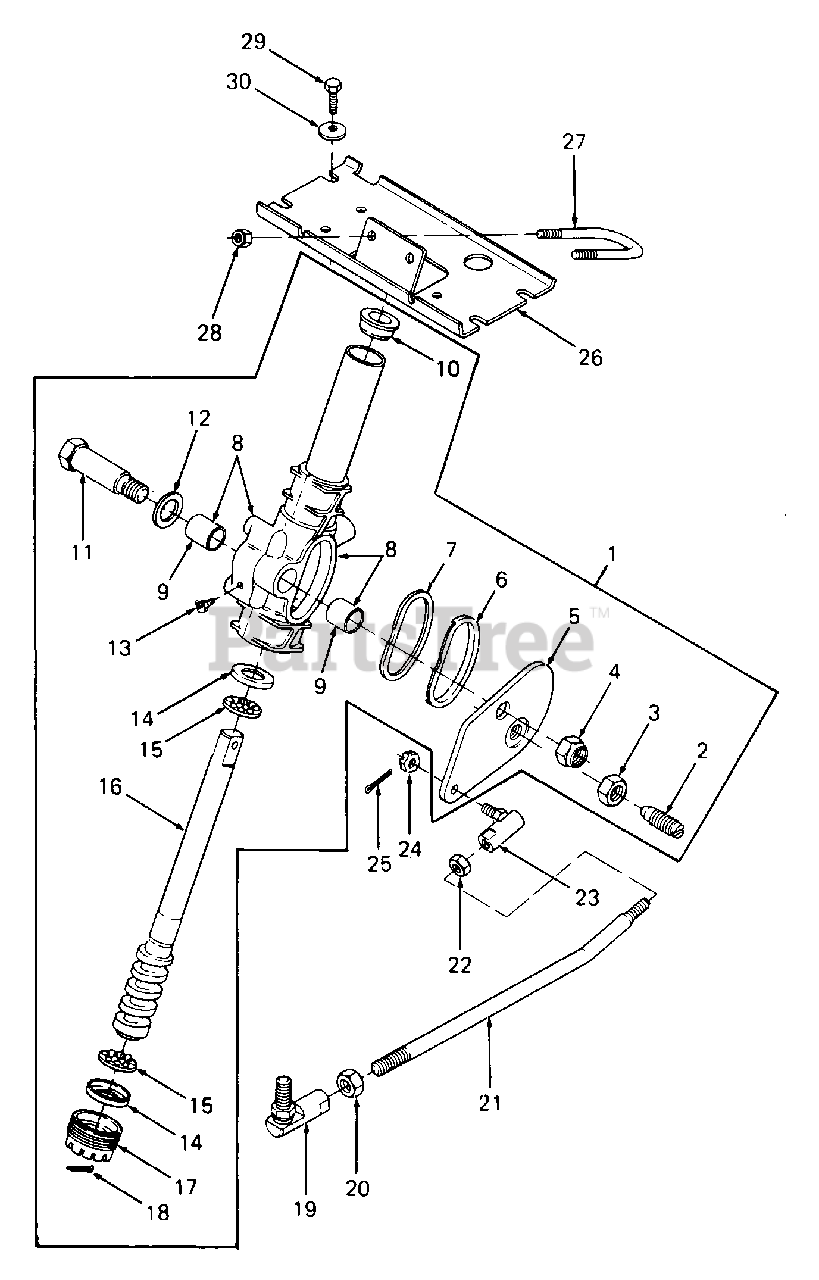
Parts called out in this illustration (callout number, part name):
1	Steering Gear Assy
2	Follower, Cam
3	Nut, Hex Jam, 9/16-18
4	Nut, Hex Crown Lock, 5/8-18
5	Arm, Steering
6	Retainer, Seal
7	Seal
8	Housing/Tube Assy
10	Bearing, Column
11	Shaft, Pivot
12	Washer, Flat, .781 X 1.25 X .027 Thk
13	Fitting, Lube, 45 Deg 1/4-28 Taper
14	Cup, Bearing
15	Retainer Assy, Ball
16	Shaft/Cam Assy
17	Plug, Adjusting
18	Pin, Cotter, 1/8 Dia X .75 Lg
19	Ball Joint
20	Nut, Hex Jam, 1/2-20 GR5
21	Link, Drag
22	Nut, Hex Jam, 3/8-24 GR5
23	Ball Joint
24	Nut, Hex Castle, 3/8-24 GR5
25	Pin, Cotter, 3/32 Dia X .75 Lg
26	Plate, Steering Support
28	Nut, Hex Center Lock, 5/16-24
29	Screw, Hex Hd Cutting, 5/16-18 X .75 Lg GR5
30	Washer, Bell, .345 X .88 X .060 Thk
